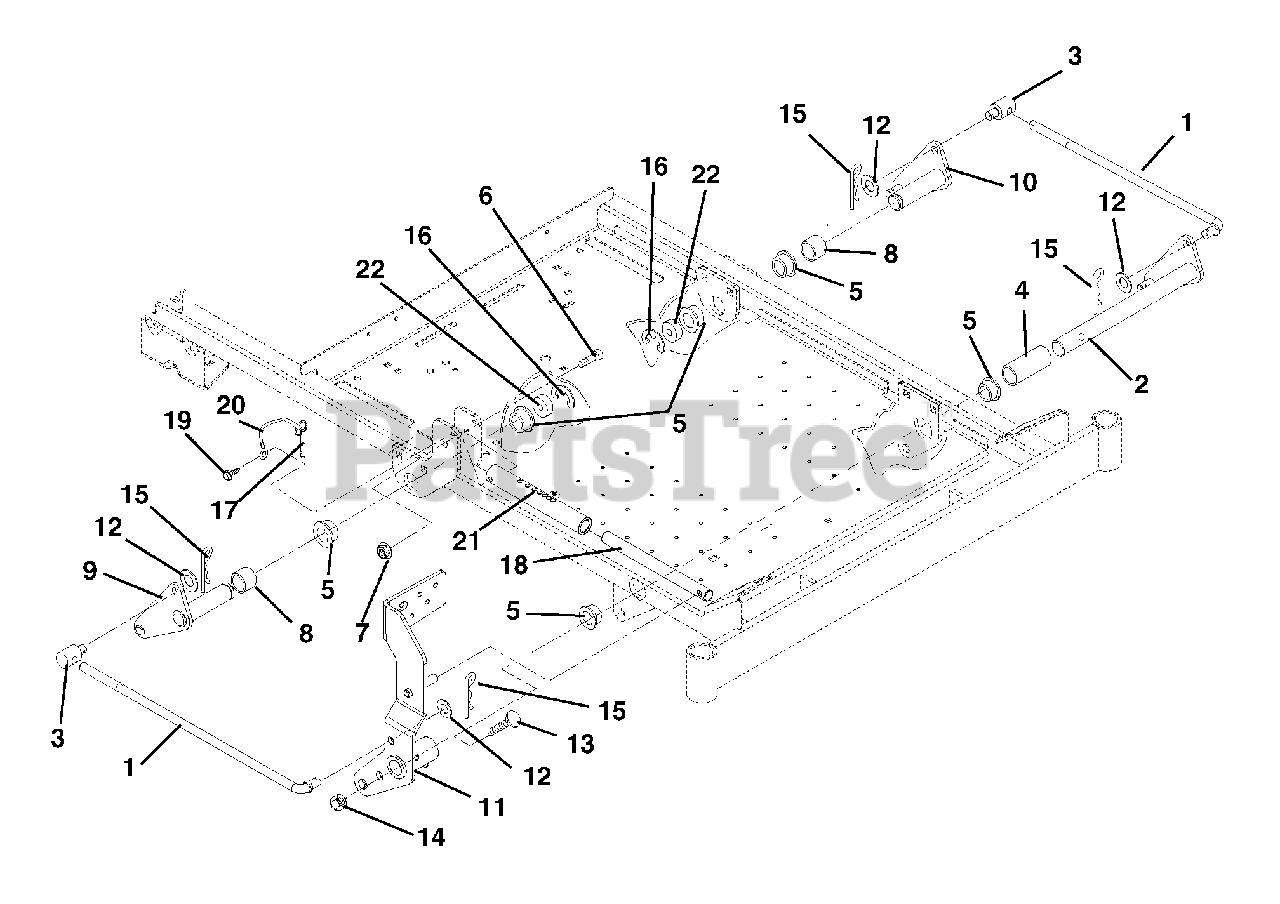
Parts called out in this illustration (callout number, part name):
1	Linkage, Lift
2	Weldment, Front Lift
3	Trunnion
4	Bushing, Front
5	Bushing-Flange 1.00 x 1.12 x .62 x 1.50 Bronze
6	Bolt, Socket Head Shield .31 x 18 x 2.00
7	Nut, .31-18 Flange Nyloc
8	Bushing, Rear
9	Weldment, Lift, Rear Right Hand
10	Weldment, Lift, Rear Left Hand
11	Weldment, Foot Pedal
12	Washer, Flat Steel .511 x 1.441 x .125
13	Bolt, Hex .38-16 x 2.00 Grade 5
14	Nut .38-16 Flange Nyloc
15	Pin, Hair External
16	Ring, Retaining .82 x 1.50 x .05
17	Pin, Spring Ball .375 O.D. x 1.50
18	Rod, Lift
19	Screw-Tapping .250-20 x .37 Hex Washer Head
20	Lanyard
21	Tube, Lift Stop
22	Spacer, Rear Lift
